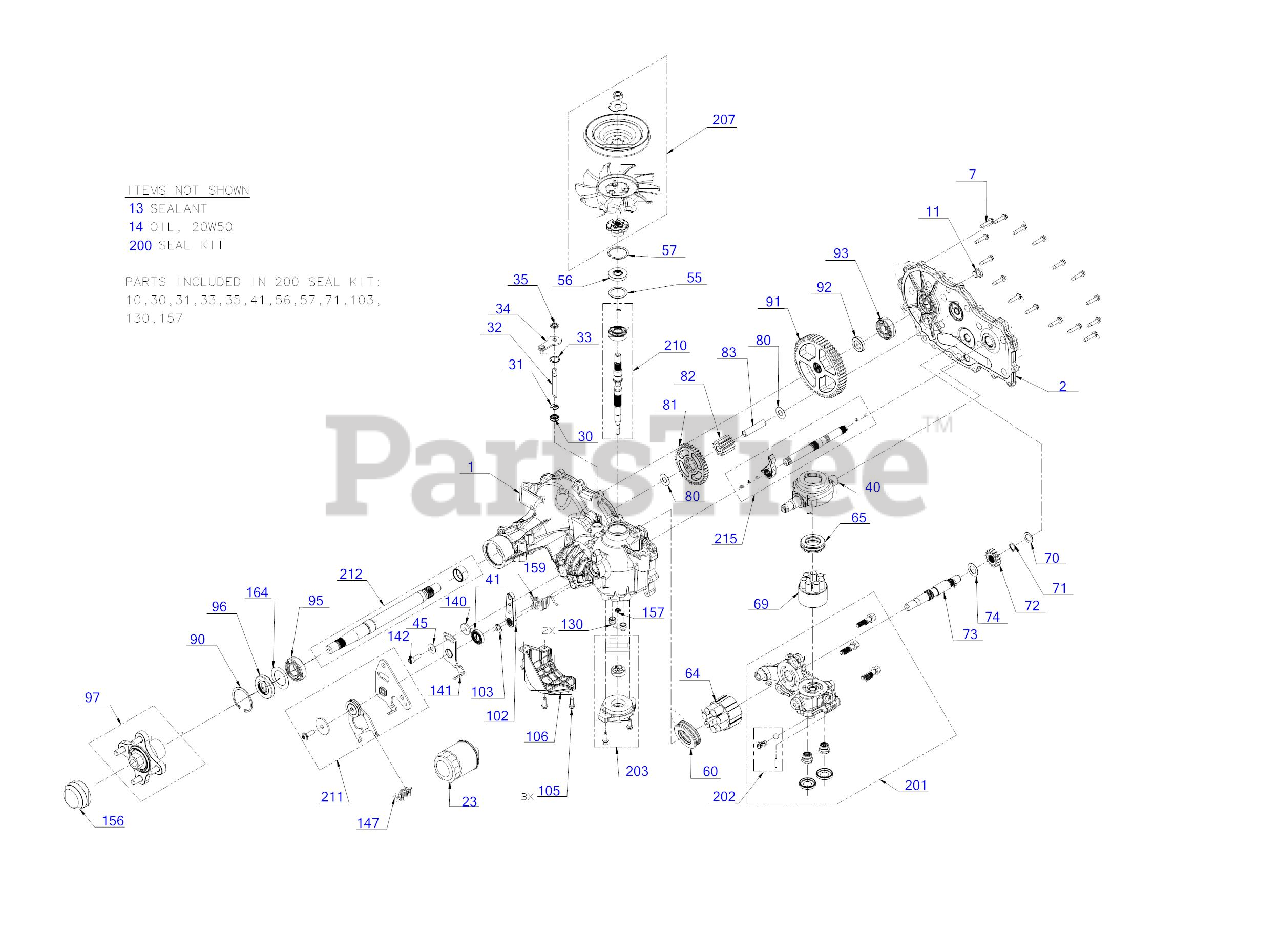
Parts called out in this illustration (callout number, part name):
1	HUOSING KIT-MAIN R
2	COVER KIT-SIDE (RH)
7	SCREW-WASHER HEAD
11	VENT PLUG
13	SEALANT-HOUSING
23	OIL FILTER
30	SEAL-LIP .375
31	RETAINING RING
32	BYPASS RODS
33	RETAINING RING
34	ARM-BYPASS
35	RETAINING RING
40	SWASHPLATE-TRUNNION
41	LIP SEAL
45	FLAT WASHER
55	WASHER 1.23X1.56X
56	LIP SEAL
57	RETAINING RING
60	THRUST BEARING
64	CYLINDER BLOCK ASSEMBLY
65	THRUST BEARING
69	BLOCK KIT-7 PISTON
70	FLAT WASHER
71	RETAINING RING
72	GEAR-16 T
73	MOTOR SHAFT
74	MOTOR SHAFT WASHER
80	WASHER
81	GEAR-43 T
82	GEAR-11 T
83	PIN-JACKSHAFT
90	RETAINING RING
91	GEAR-54 T
92	SPACER .75X1.32X.257
93	BALL BEARING
95	BALL BEARING
96	OIL SEAL
97	HUB-4 BOLT WHEEL
102	BRAKE LEVER
103	RETAINING RING
105	SCREW
106	GUARD-FILTER (RH)
130	TUBE-CHARGE TRIPLE O-RING
140	SPACER .32 x 1.005 x .179
141	ARM-NEUTRAL (RH)
142	SCREWS KIT-RTN
147	EXTENSION SPRING
156	COVER-NUT
157	KIT-GEROTOR SEAL
159	TORSION SPRING CCW
164	SPACER
200	SEAL KIT
201	CENTER SECTION RH CHARGE KIT
202	KIT-CHARGE RELIEF
203	CHARGE KIT
207	KIT-FAN & PULLEY
207	FAN-7.0 (10 BLADE)
207	HUB-PULLEY
207	WASHER-SLOTTED
207	NUT-JAM
209	PULLER KIT-HUB
210	SHAFT KIT-INPUT
211	KIT - RETURN CW
212	SHAFT KIT-AXLE
215	OUTPUT SHAFT KIT (RH)
